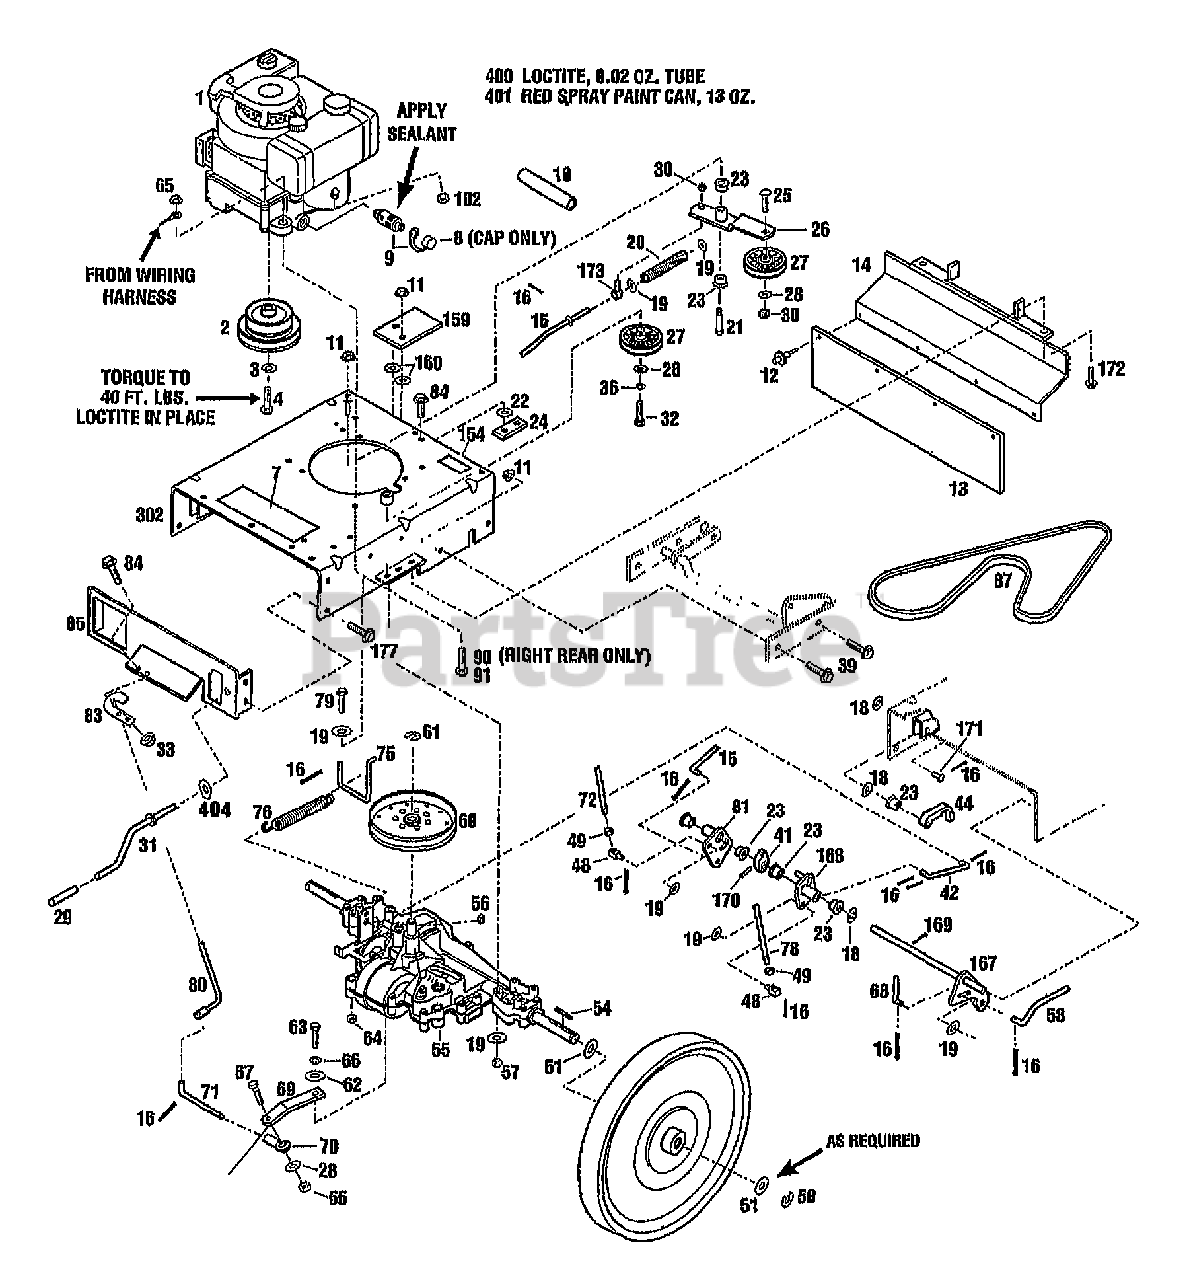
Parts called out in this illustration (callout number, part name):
2	PULLEY-ENGINE
3	WASHER-LK .438 ZP
4	SCR-HHC 7/16-20X1.75 (TORQUE TO 40FT. LBS. LOCTITE IN PLACE)
7	DECAL-WARNING
9	ASSM-OIL VALVE (APPLY SEALANT)(INCL. 8)
10	HOSE-OIL DRAIN
11	NUT-HFLK 3/8-16 ZP
12	RIVET-POP 3/16 X 5/8
13	FLAP-SAFETY
14	BRACKET-FLAP
15	ROD-LOWER TRANS
16	PIN-COTTER .093X.625
18	WASHER-FLAT .88X.5X.06 ZP
19	WASHER-FLAT 5/16 SAE
20	SPRING-COMPRESSION
21	SCR-SHLDR 3/8-16
22	WASHER-.865X.281X.1793
23	BUSHING-.5X.5 NYLON FLNG
24	NUT-SPEED
25	SCR-CARR 3/8-16X1.75 G5 ZP
26	ASSM-IDLER ARM ZP
28	WASHER-FLAT 3/8 SAE
29	GRIP-PLASTIC
30	NUT-LOCK 3/8-16
31	ASSM-CRANK LIFT
32	SCR-HH 3/8-16X1.75 G5 ZP
33	NUT-HF/LK 1/4-20 ZP
36	WASHER-LK .375 @ DEPL
39	SCR-HFLK 3/8-16X1.00 ZP
41	CAM-INTERLOCK
42	ROD-LOWER BRAKE
44	LATCH-INTERLOCK
48	BLOCK-SWIVEL ZP
49	NUT-HEX JAM 5/16-18
50	RING-RET."E".577 ID
51	WASHER-1.5X.755X.062 (AS REQUIRED)
52	ASSM-WHEEL & TIRE
54	Key, 3/16X1.50
56	KEY-WOODRUFF .188X.75
57	NUT-TOP/LK 5/16-18 ZP
58	ROD-LOWER BLADE
60	PULLEY-TRANSAXLE
61	RING-RETAIN .625 ID
62	WASHER-FLAT 1/4 SAE
63	SCR-HH 1/4-28X.75 G5 ZP
64	NUT-HFLK 5/16-18 ZP
65	NUT-H/LK 3/8-16 (FROM WIRING HARNESS)
66	WASHER-LK .25 ZP
67	SCR-HH 3/8-16X1.25
68	ROD-UPPER BLADE
69	ARM-TRANSMISSION ZP
70	JOINT-BALL
71	ROD-SHIFT LINK
72	ROD-UPR TRANSMISSION
75	ROD-SPRING ATTACHMENT
76	SPRING-EXTENSION
78	ROD-UPPER BRAKE
79	SCR-HH 5/16-18X2.75 G5 ZP
80	LEVER-SHIFT
81	ASSM-CLUTCH ARM ZP
83	BRKT-SHIFT ROD MTG
84	SCR-HFLK 1/4-20X.50 ZP
85	PLATE-BACK
90	SCR-THRD FRM 3/8-16X1.50 (RIGHT REAR ONLY)
91	SCR-HH 3/8-16X1.0 (RIGHT REAR ONLY)
102	NUT-HEX 1/4-20 ZP {34069}
154	DECAL-AMERICAN LEGEND-SM
159	SHIELD-ENGINE {34068,34069}
160	WASHER-FLAT 1.25X.406X.179 {34068,34069}
167	SHAFT-PIVOT ZP
168	ASSM-BRAKE ARM ZP
169	PIN-COTTER .120X1.00 ZP
170	PIN-ROLL .156X1.0
171	PIN-CLEVIS .5X1.25
172	SCR-HFLK 5/16-18X.75
173	BOLT-EYE
177	SCR-HFLK 5/16-18X.625 STH
302	ASSM-FRAME
400	LOCTITE-242 (.5 ML TUBE)
401	PAINT-RED SPRAYCAN POWDER (13 OZ.)
402	KIT-SVC 5.5HP HIGHWHEEL MWR {34067,34066}
402	KIT-SVC 8HP HIGHWHEEL MWR {34068,34069}
403	CAP-OIL DRAIN
404	WASHER-NYLON
